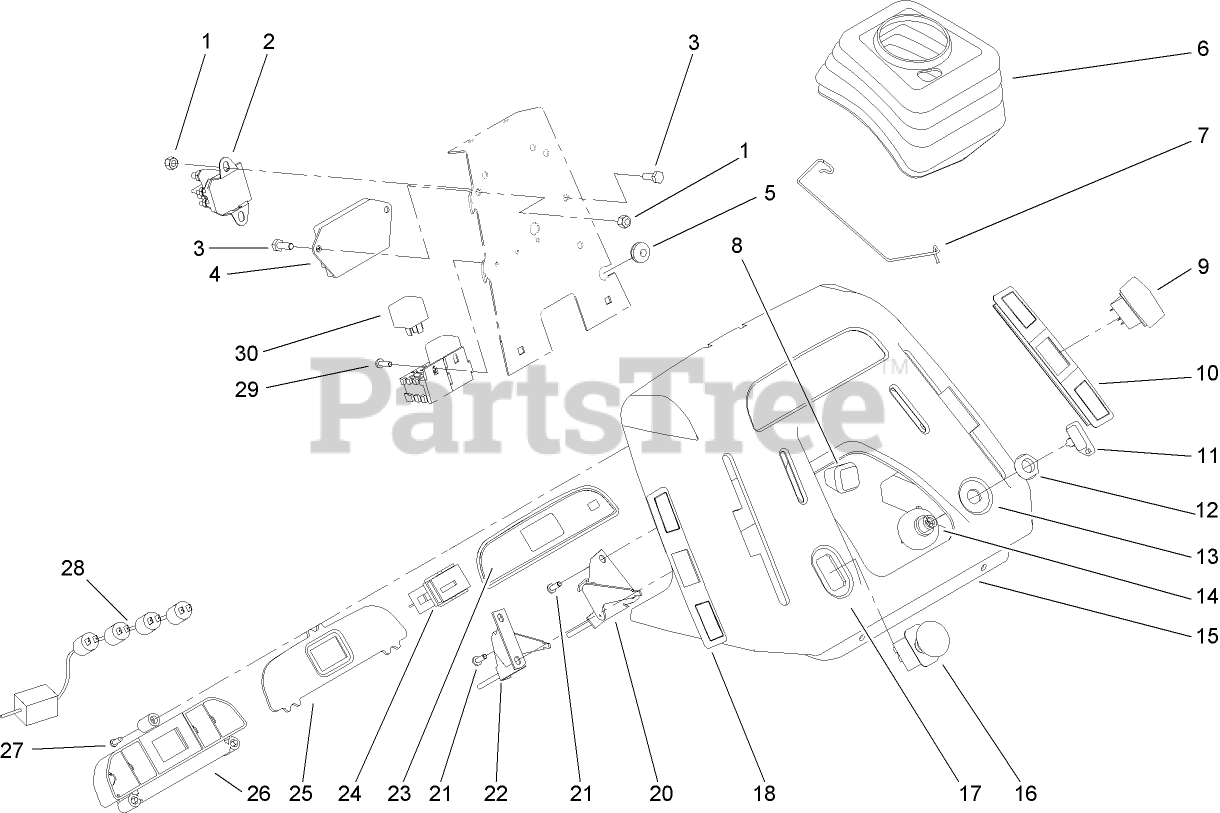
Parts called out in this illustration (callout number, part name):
1	NUT-LOCK, NI
2	SOLENOID-STARTER
3	SCREW-HH
4	MODULE-NMIR, LOW BATTERY
5	GROMMET-RUBBER
6	BOOT-STEERING
7	CLIP-BOOT
9	SWITCH-CRUISE
10	COVER-SLOT, RH
11	KEY-IGNITION
13	DECAL-THROTTLE, IGNITION
14	SWITCH-IGNITION
16	SWITCH-PTO,ON-ON-NONE
17	DECAL-PTO / CHOKE
18	COVER-SLOT, LH
20	CONTROL-THROTTLE (TWIN)
22	CHOKE CONTROL ASM
24	HOURMETER
25	LENS-DASH
26	HOUSING-LIGHT, INDICATOR
27	SCREW
28	HARNESS-4 LAMP
29	SCREW-PPHTF
30	RELAY
